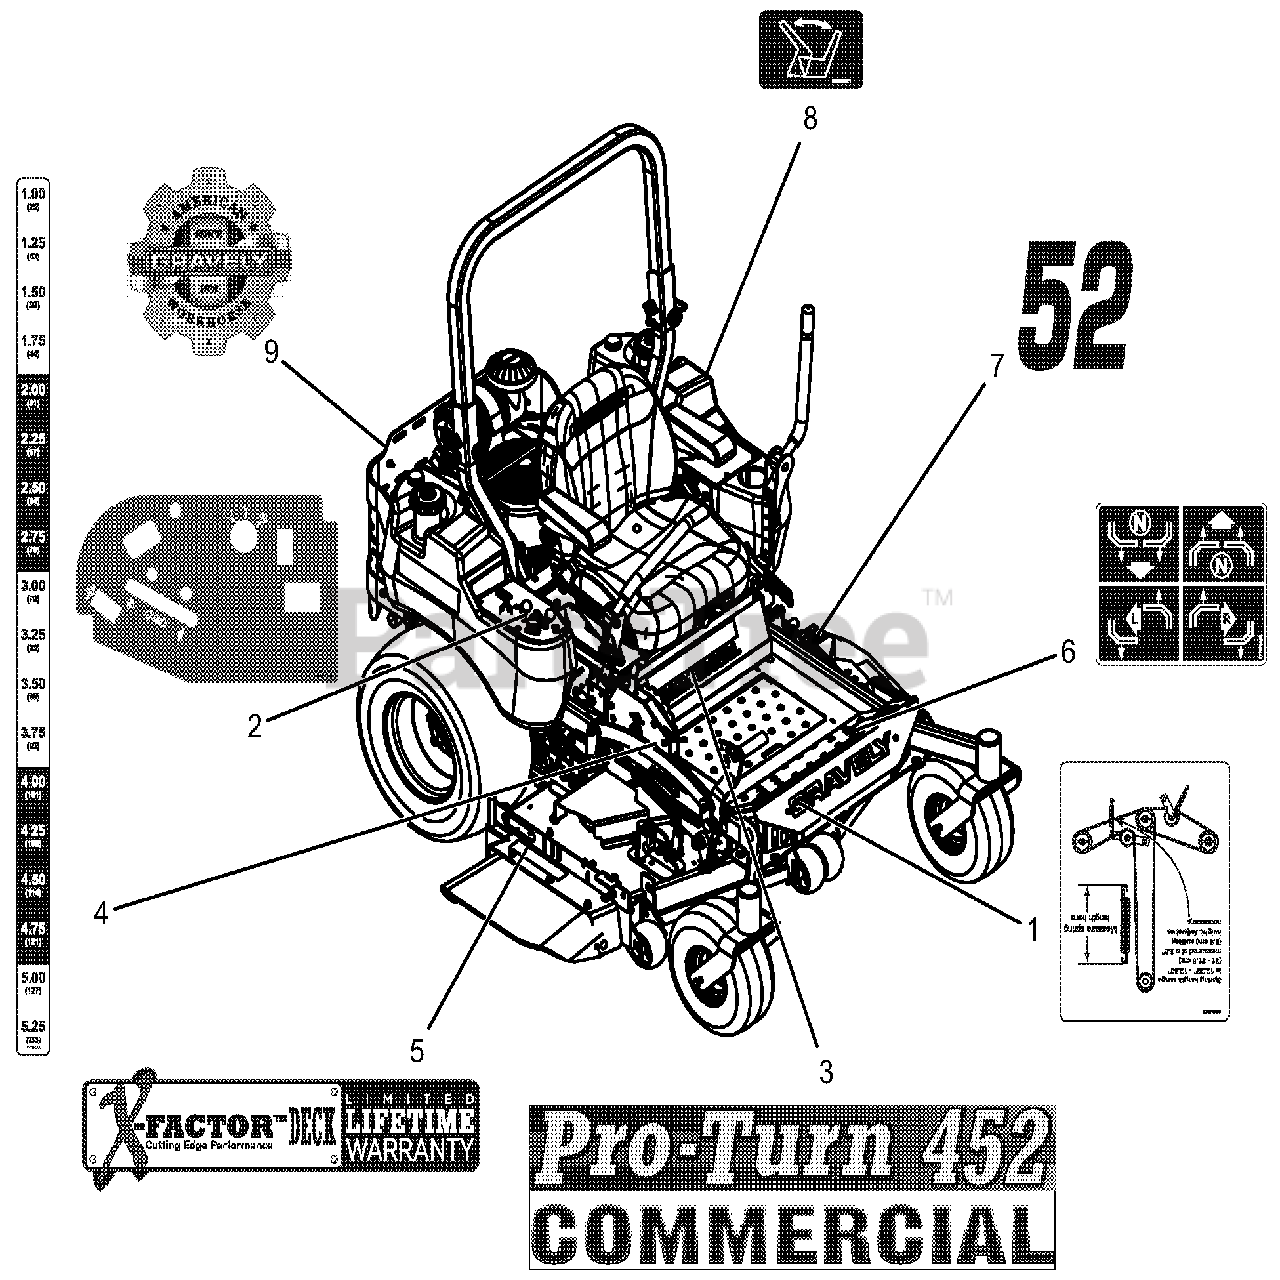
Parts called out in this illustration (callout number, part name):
1	DECAL, BELT ROUTING
2	DECAL, CONTROL PANEL
3	DECAL, PT452
4	DECAL, PT400 HEIGHT OF CUT
5	DECAL, X-FACTOR DECK
6	DECAL, INSTRUCTIONAL - STEERING
7	DECAL, 52"
8	DECAL, SEAT RELEASE
9	DECAL, GRAVELY HERITAGE-LARGE
